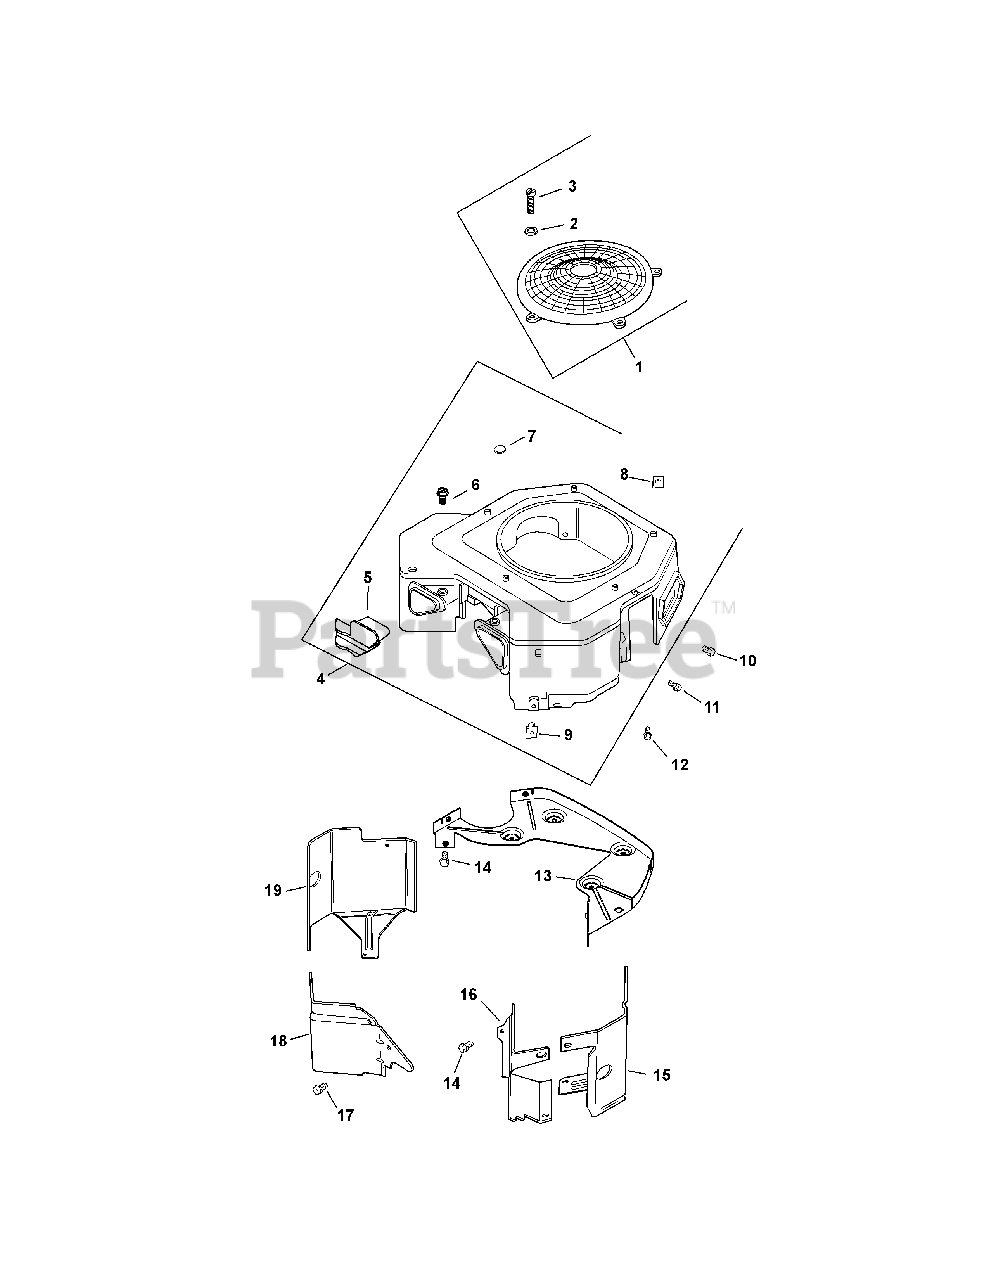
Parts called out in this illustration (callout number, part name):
1	KIT, FIXED GUARD
2	WASHER, FLAT 7/32''
3	SCREW, LBD SCKT PAN M5X0.8X10
4	KIT, BLOWER HOUSING ASSEMBLY
5	COVER, BLOWER HOUSING-MOLDED
6	SCREW, WSH HD TAP #8-18X1/2''
7	PLUG, BUTTON 9/16
10	SCREW, FLG THD F RM M5X.8X16
11	SCREW, FLG THD FRM M5X0.8X16
12	SCREW, FLG THD FRM M5X.8X20
13	KIT, BACKING PLATE
14	SCREW, FLG THD FRM M6X1.0X16
15	KIT, CYL BAFFEL #2 SIDE
16	BAFFLE, VALLEY #2 CYLINDER
17	SCREW, FLG THD FRM M5X.8X10
18	BAFFLE, VALLEY #1 CYLINDER
19	KIT, CYL BAFFEL #1 SIDE
